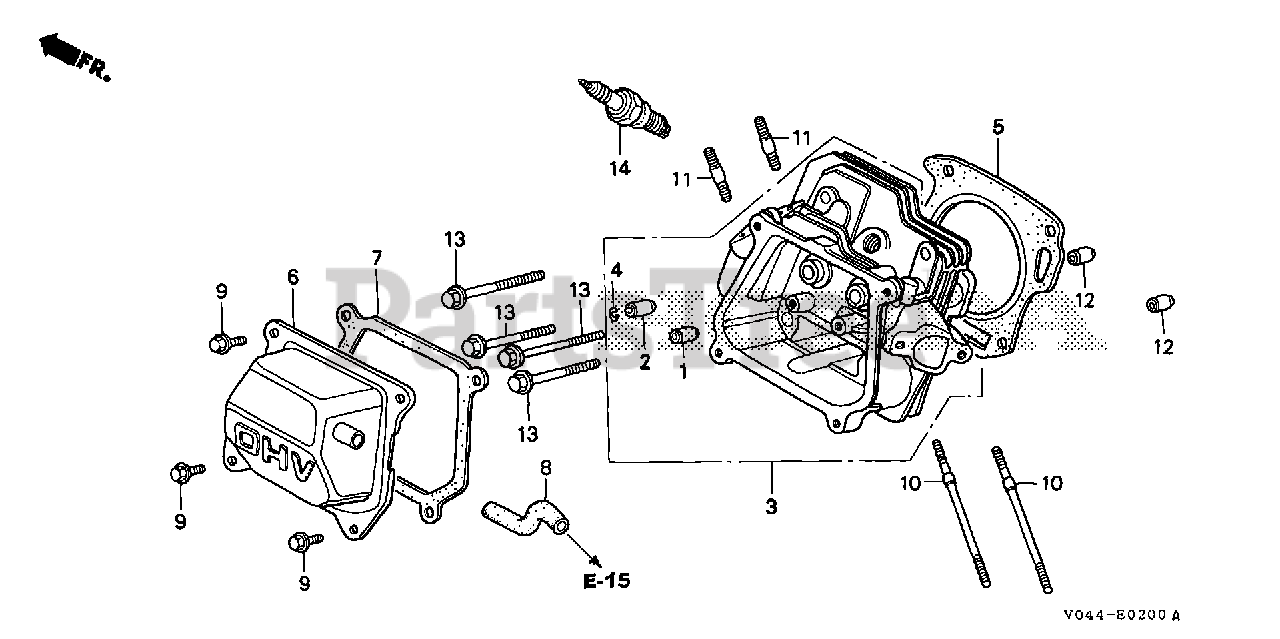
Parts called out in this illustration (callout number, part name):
1	GUIDE, VALVE (OVER SIZE) Use from Engine SN 6324986.
2	GUIDE, EX. VALVE (OS)
3	CYLINDER HEAD
4	CLIP, VALVE GUIDE Use from Engine SN 1231803.
5	GASKET, CYLINDER HEAD (NIPPON LEAKLESS)
6	COVER, HEAD
7	GASKET, CYLINDER HEAD COVER
8	TUBE, BREATHER
9	BOLT, FLANGE (6X12) (CT200)
10	BOLT, STUD (6X109)
11	BOLT, STUD (8X32)
12	PIN A, DOWEL (10X16)
13	BOLT, FLANGE (8X60)
14	SPARK PLUG (BPR5ES) (NGK)
14	SPARK PLUG (W16EPR-U) (DENSO)
